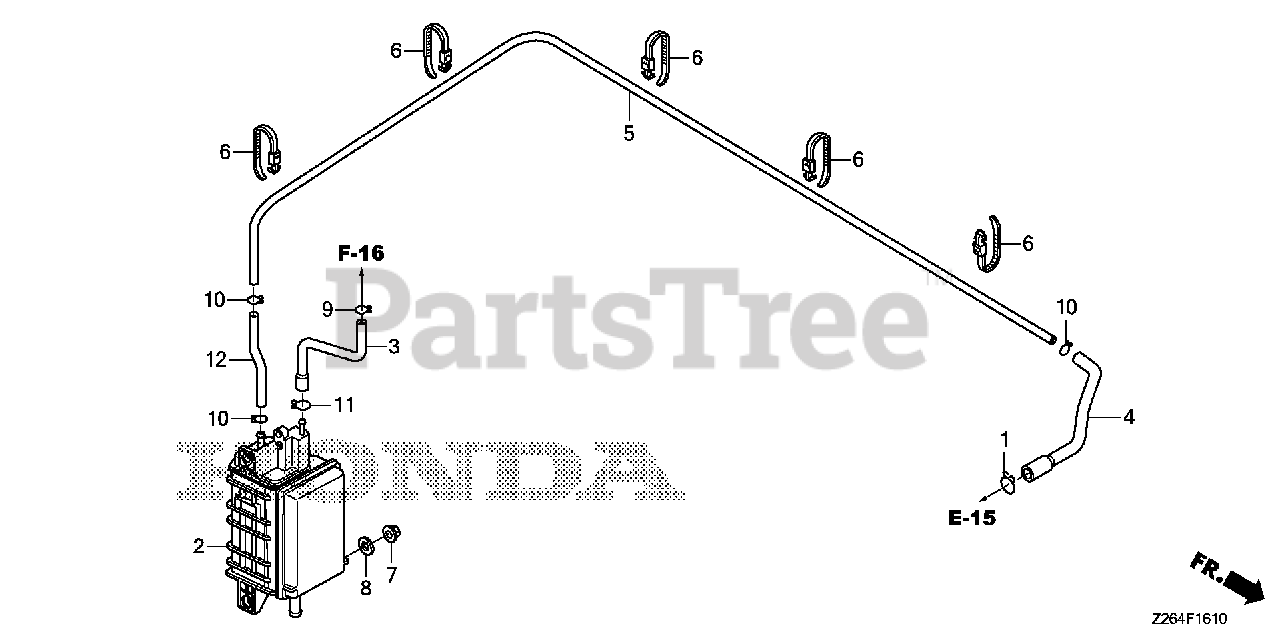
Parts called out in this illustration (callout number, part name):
1	CLIP, BREATHER TUBE
2	CANISTER ASSY.
3	TUBE, CANISTER CHARGE
4	TUBE, CANISTER PURGE
5	PIPE, CANISTER PURGE
6	TIE, CABLE
7	NUT, FLANGE (6MM)
8	WASHER, PLAIN (6MM)
9	CLIP, TUBE (B8)
10	CLIP, TUBE (B12) Use from Engine SN 2086984.
11	CLIP, TUBE (C9)
12	BULK HOSE, FUEL (7.5X8000) (7.3X160)
